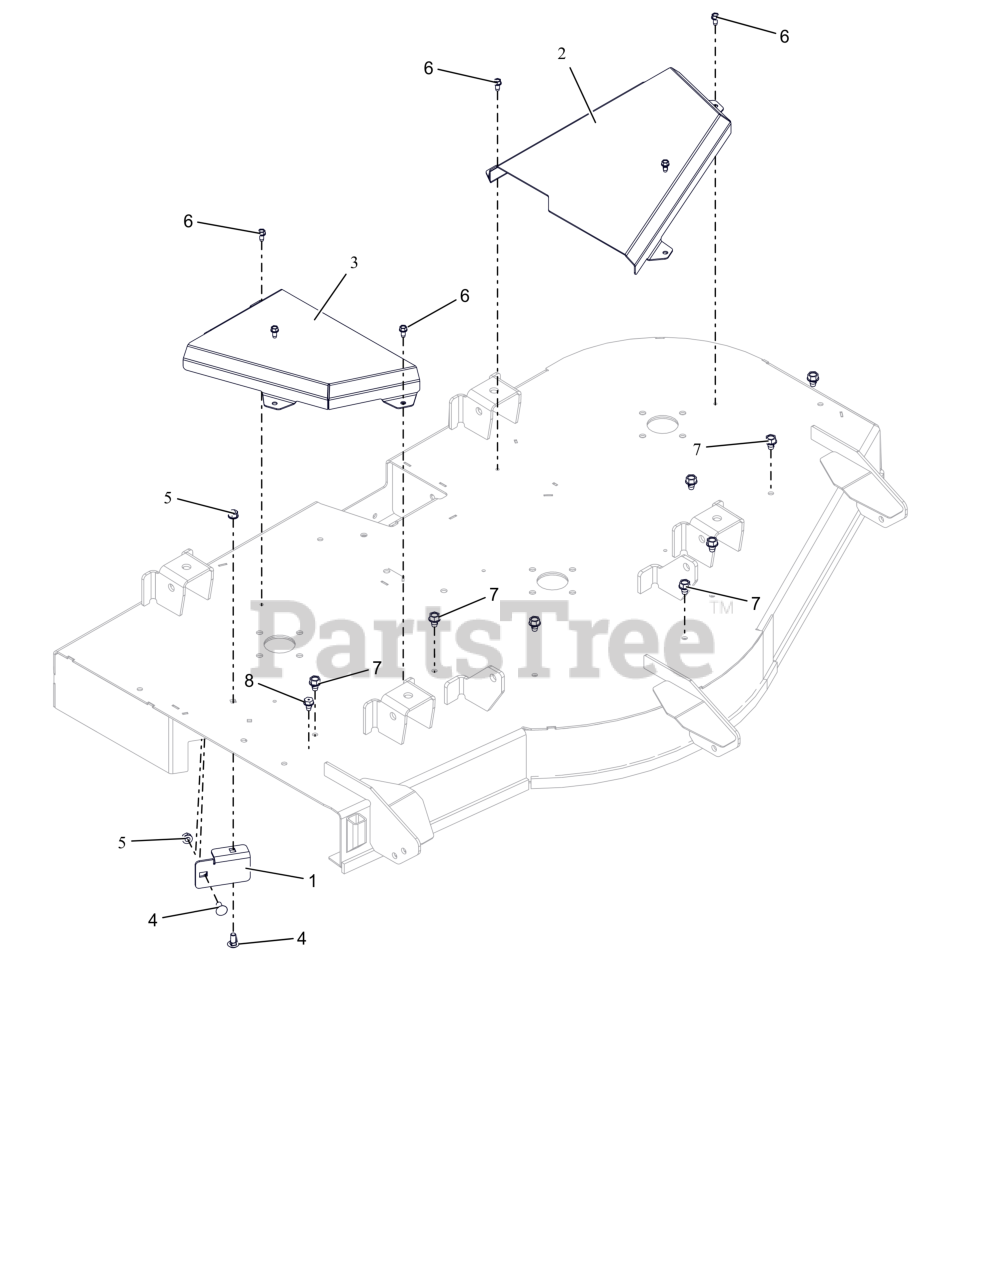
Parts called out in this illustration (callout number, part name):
1	STRIP, DEFLECTOR - 52"
2	COVER, LH BELT - 52" (RED)
3	COVER, RH BELT - 52" (RED)
4	BLT,RHSN .31-18X.75 G5 ZCC
5	NUT-LK-TOP-FLG .312-18 GF ZCC
6	SCR-TAP .25-20X.50 HWH ZCC
7	SCR,TAP .375-16X.50 HWH TR ZCC
8	SCR,TAP .312-18X.50 HWH TR ZCC
